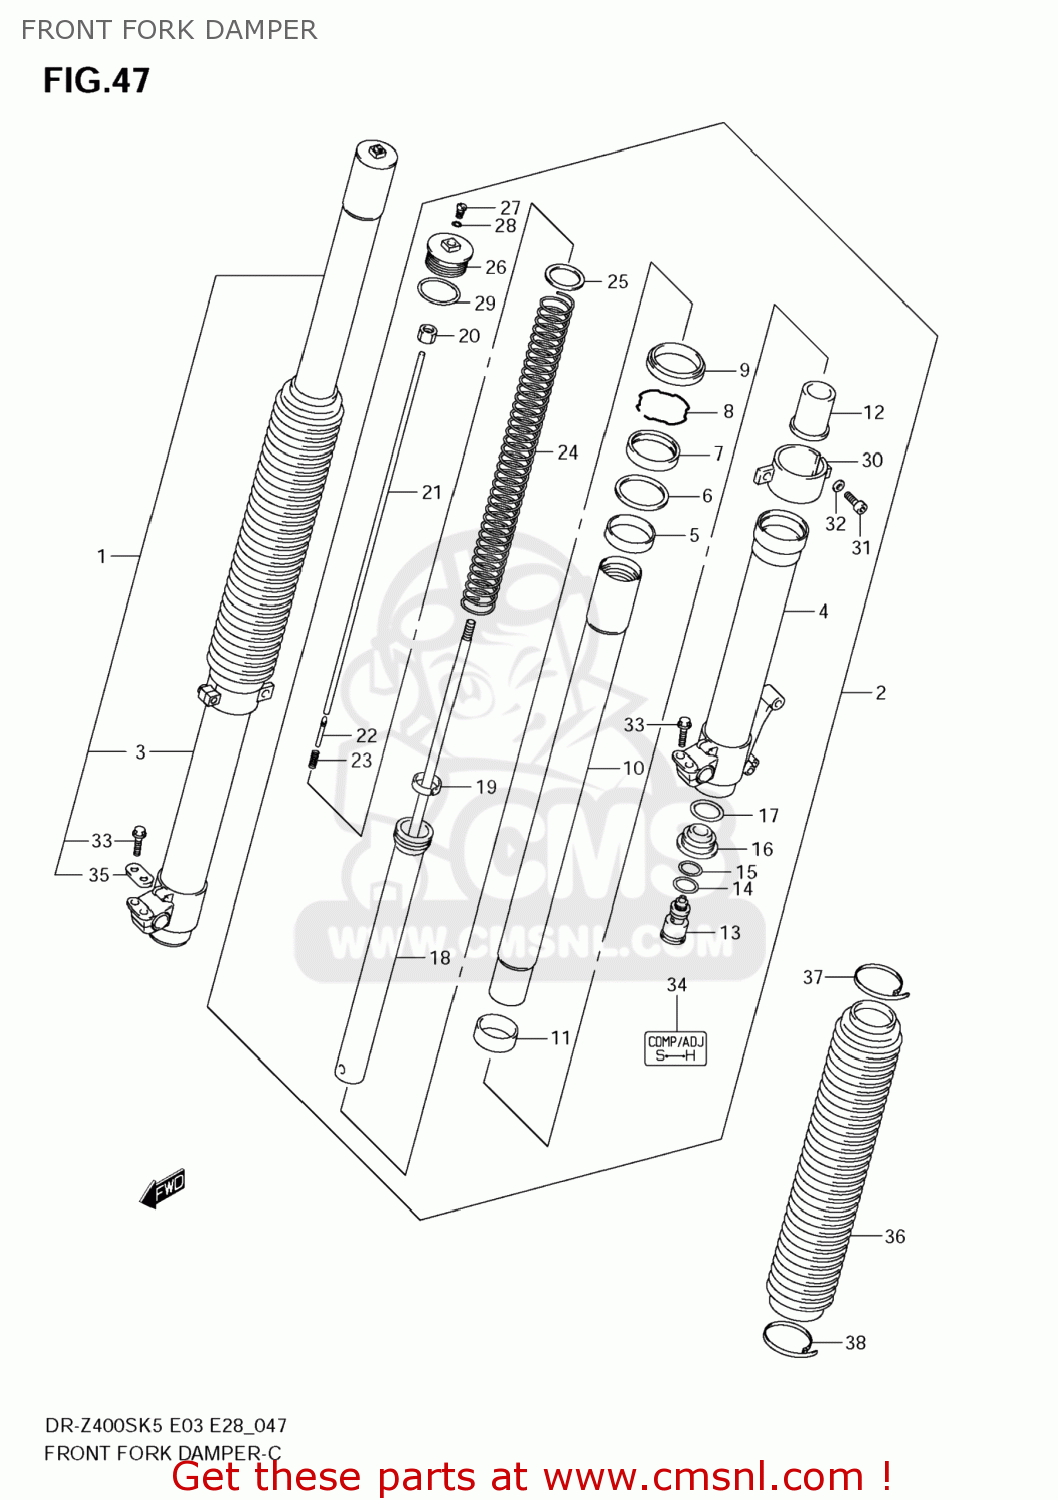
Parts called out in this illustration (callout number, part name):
1	DAMPER ASSY,FR FORK,R
2	DAMPER ASSY,FR FORK,L
3	TUBE,OUTER,R
4	TUBE,OUTER,L
5	BUSH,GUIDE
6	SPACER,SEAL
7	SEAL,OIL
8	RING,STOPPER
9	SEAL,DUST
10	TUBE,INNER
11	BUSH,SLIDE
12	PIECE,OIL LOCK
13	BOLT,CTR
14	O RING
15	O RING
16	PLATE,END
17	O RING
18	ROD,FR DAMPER
19	BUSH,SLIDE
20	NUT
21	ROD,PUSH
22	NEEDLE
23	SPRING,PUSH ROD
24	SPRING,FR(K=8.63N/0.88KG)
25	JOINT,SPRING
26	BOLT,FORK
27	BOLT,PLUG
28	O RING,PLUG
29	O RING
30	HOLDER,BOOT
31	BOLT
32	WASHER(5.5X10X1)
33	BOLT,HANDLE HOLDER(8X35)
34	LABEL
35	COVER,AXLE HOLDER
36	BOOT
37	BAND,BOOT UPR
38	BAND,BOOT LWR
